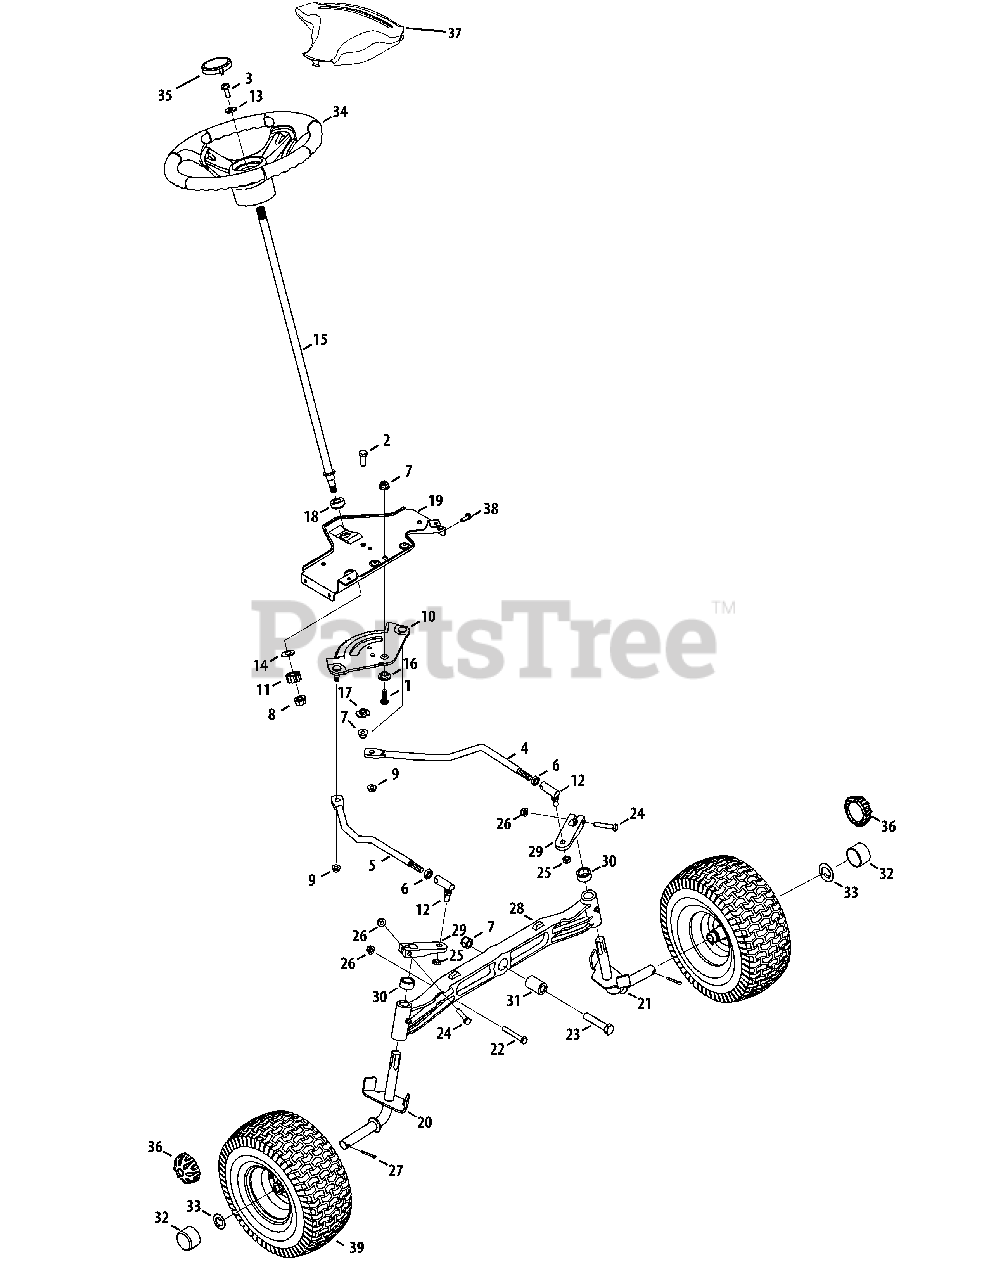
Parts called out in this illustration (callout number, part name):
1	Screw, 3/8-16 x 1.0
2	Hex Screw 3/16 x 1.00
3	Hex Screw 5/16-18 x 1.00 Special
4	Link, Drag LH
5	Link, Drag RH
6	Hex Jam Nut 7/16-20
7	Flange Lock-Nut 3/8-16 Gr. F Nylon
8	Flange Lock Nut, 7/16-20
9	HEX FLANGE NUT
10	Steering Gear, 11/90 Ratio
11	Steering Pinion Gear
12	Ball Joint, 7/16 - 20
13	Flat Washer .406 ID x .875 DE x .105
14	Flat Washer .510 x 1.120 x .060
15	Steering Shaft .625 OD x 24.25
16	Shoulder Spacer .385 x 1.25 x .3025
17	Spacer .38 x 1.375 Special
18	Hex Flange Bearing 5/8
19	Steering Support Bracket
20	Axle Ass'y RH .750 Dia
21	Axle Ass'y LH .750 Dia.
22	Hex Bolt 5/16-18 x 2.25
23	Hex Cap Screw, 3/8-16 x 2.5
24	Hex Screw 5/16-18 x 1.75" Lg.
25	Hex Cent L-Nut 3/8-24
26	Flange Locknut 5/16-18 Gr. F, Ny lon
27	Cotter Pin 5/32" Dia.
28	Pivot Bar (cast)
29	Steering Block
30	Spacer .710 ID x .125 OD x .56
31	Spacer .385 x 1.0 x 1.5075
32	Hub Cap (w/ball bearings)
33	Flat Washer .755 x 1.92 x .060 (w/ball bearings)
34	Steering Wheel, Standard Grip
34	Steering Wheel, Softgrip
35	Steering Wheel Cap (spig) logo
36	Hub Cap
37	Steering Wheel Cover (w/o sprigs)
38	SCREW 5/16-18 x .750
39	See "Front and Rear Wheels"
